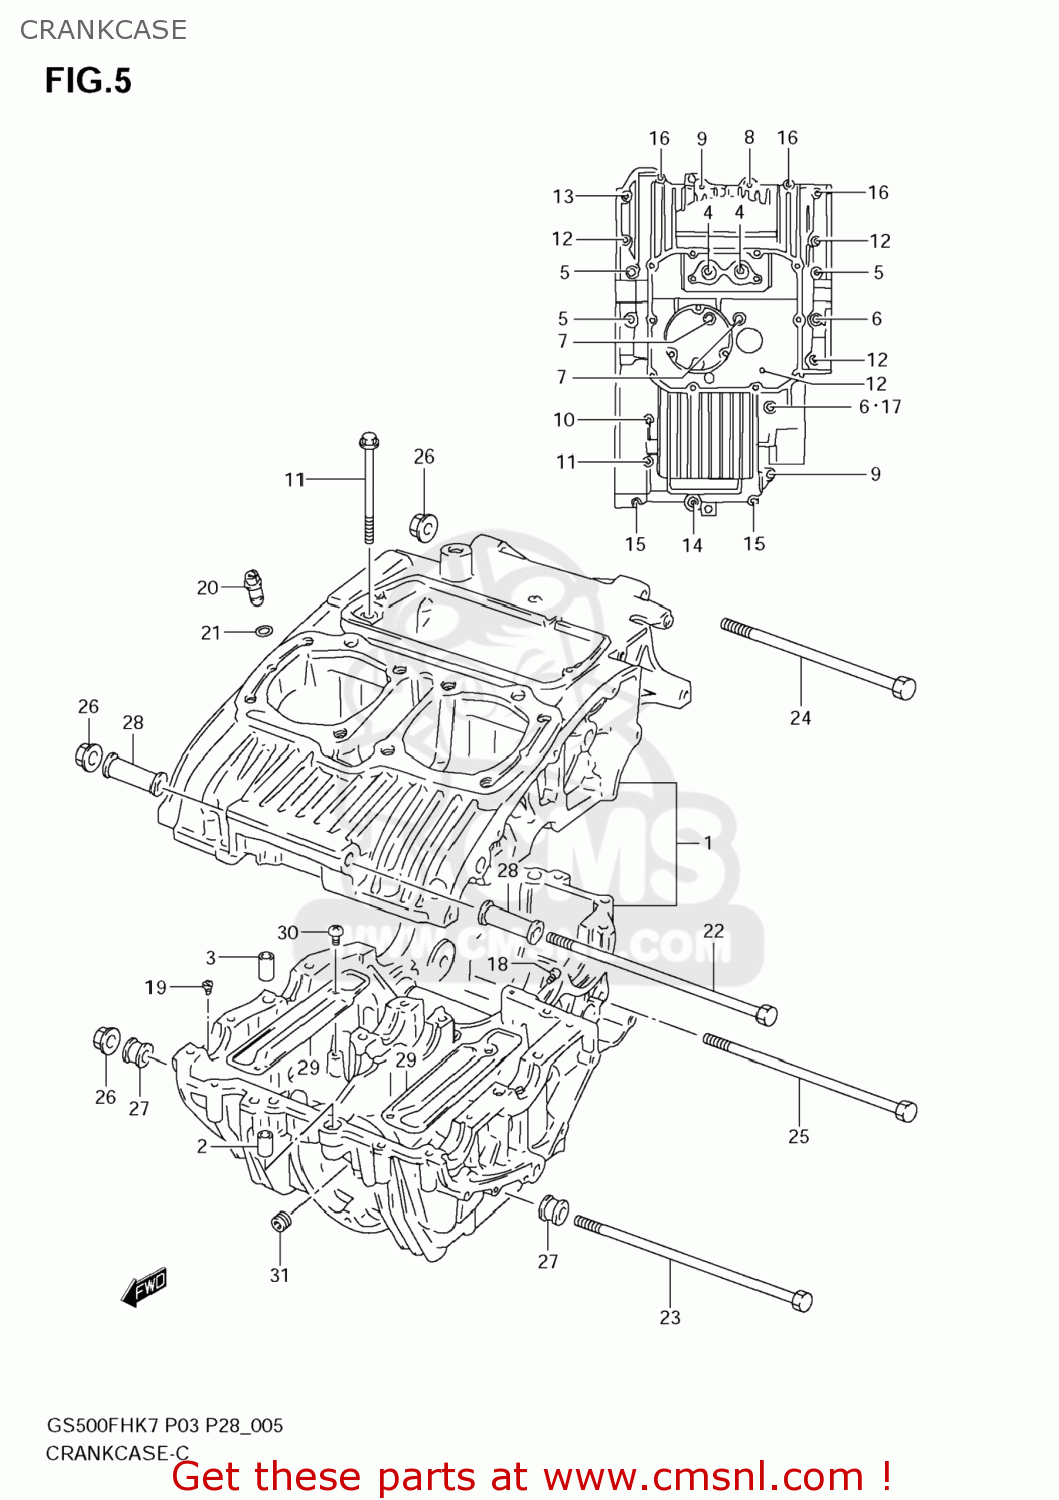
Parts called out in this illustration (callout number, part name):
1	CRANKCASE SET
2	PIN(10.4X13X22)
3	PIN(8.4X11X20)
4	BOLT
5	BOLT(8X125)
6	BOLT(8X110)
7	BOLT(8X100)
8	BOLT
9	BOLT
10	BOLT(6X125)
11	BOLT(6X105)
12	BOLT
13	BOLT
14	BOLT
15	BOLT
16	BOLT
17	GASKET(8.2X14X1) (NAS)
18	JET,AIR
19	JET
20	JET
21	O RING(D:1.05,ID:3.1)
22	BOLT(10X255)
23	BOLT(10X245)
24	BOLT(10X170)
25	BOLT(10X160)
26	NUT
27	SPACER,ENG MTG(L:16.8)
28	SPACER,ENGINE MOUNT(L:65)
29	PLATE,OIL SEPARATOR
30	BOLT(6X12)
31	JET,OIL PAN GALLERY
